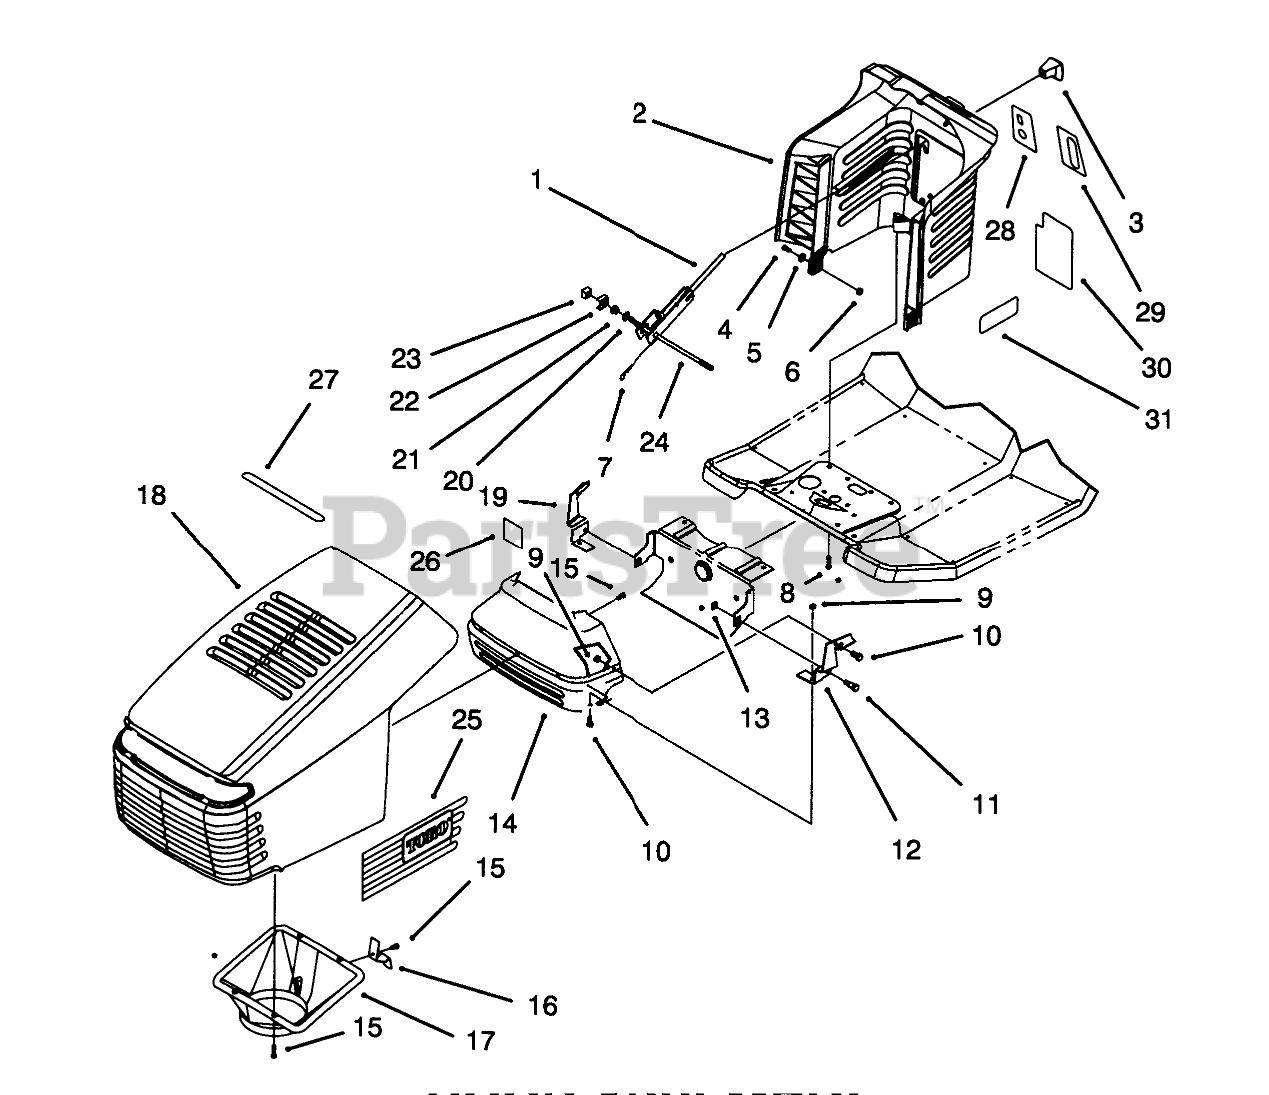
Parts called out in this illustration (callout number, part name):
1	Lever-Deck Engage
2	Tower-Steering
3	SHIFT KNOB
4	SCREW-HH
5	WASHER-PLAIN
6	NUT-LOCK, NI
7	PIN-COTTER
8	SCREW-HWH
9	NUT-LOCK, NI
10	SCREW-HH
11	BOLT-SHOULDER
12	Bracket-Hinge L.H.
13	NUT-RETAINER
14	Shield-Heat
15	SCREW-PLASTITE
16	HOOD LATCH
17	DUCT-AIR
18	HOOD ASM
19	Bracket-Hinge R.H.
20	WASHER-FLAT
21	NUT-FLANGE
22	ROD-CLAMP PIVOT
23	NUT-WEDGE
24	ROD-TOWER PIVOT
25	DECAL - HOOD RIGHT
26	TAPE-FOIL
27	DECAL-AIR DUCT
28	DECAL-IGNITION/LIGHTS
29	DECAL
30	DECAL-DECK, ENGAGE
31	DECAL - TOWER
